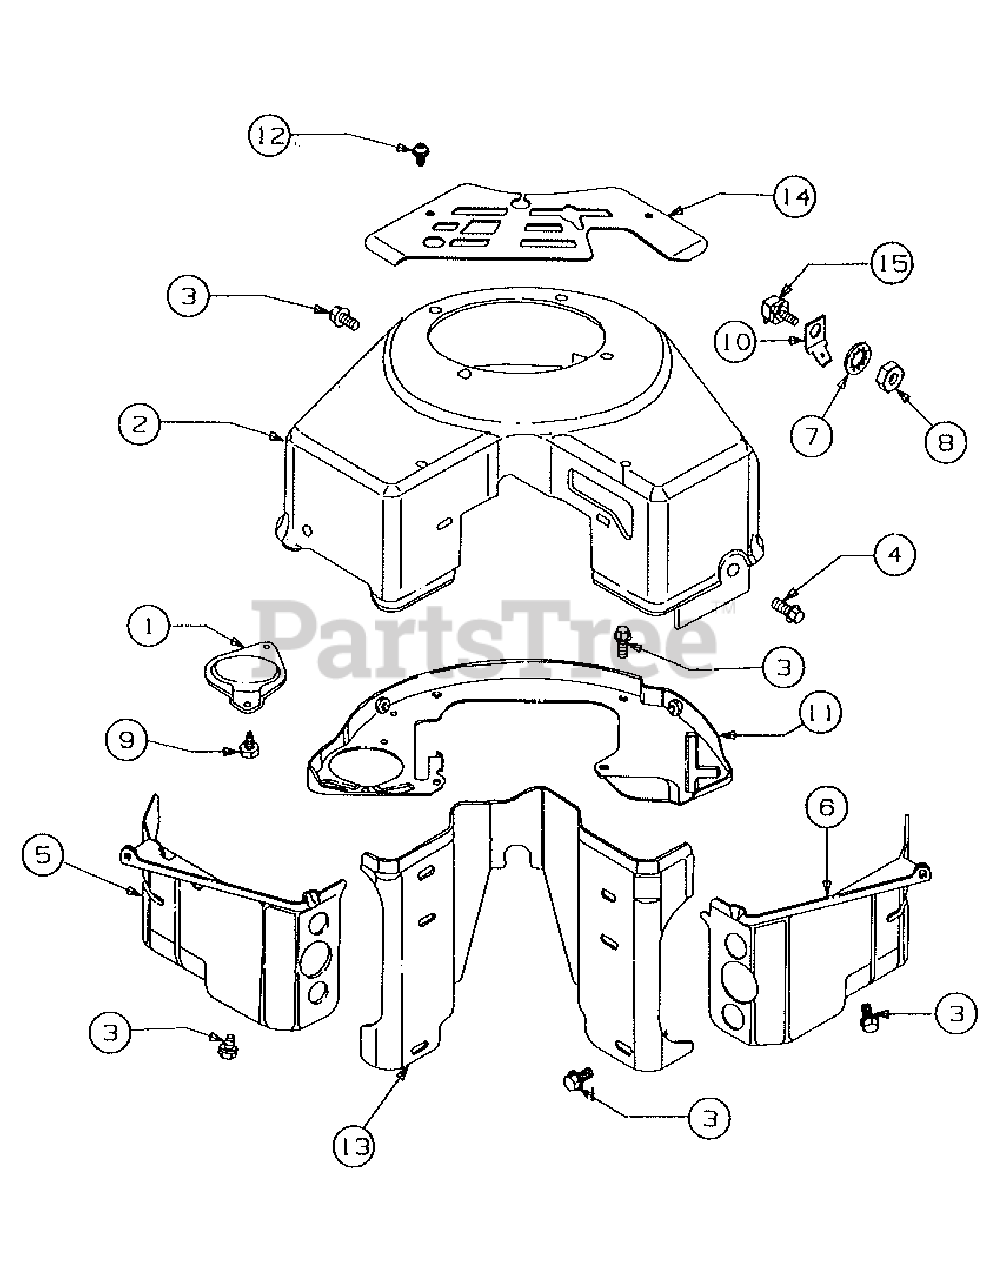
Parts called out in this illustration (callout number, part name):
1	Cover, Starter
2	Housing, Blower
3	Screw, Sem
4	Screw, Sem
5	Cover, Air Guide
6	Cover, Air Guide
7	Washer, Lock
9	Screw, Sem
10	Terminal Spade
11	Back Plate Assembly
12	Screw, Sem
13	Valley Cover, Air Guide
14	Cover, Carburetor
15	Insulator
